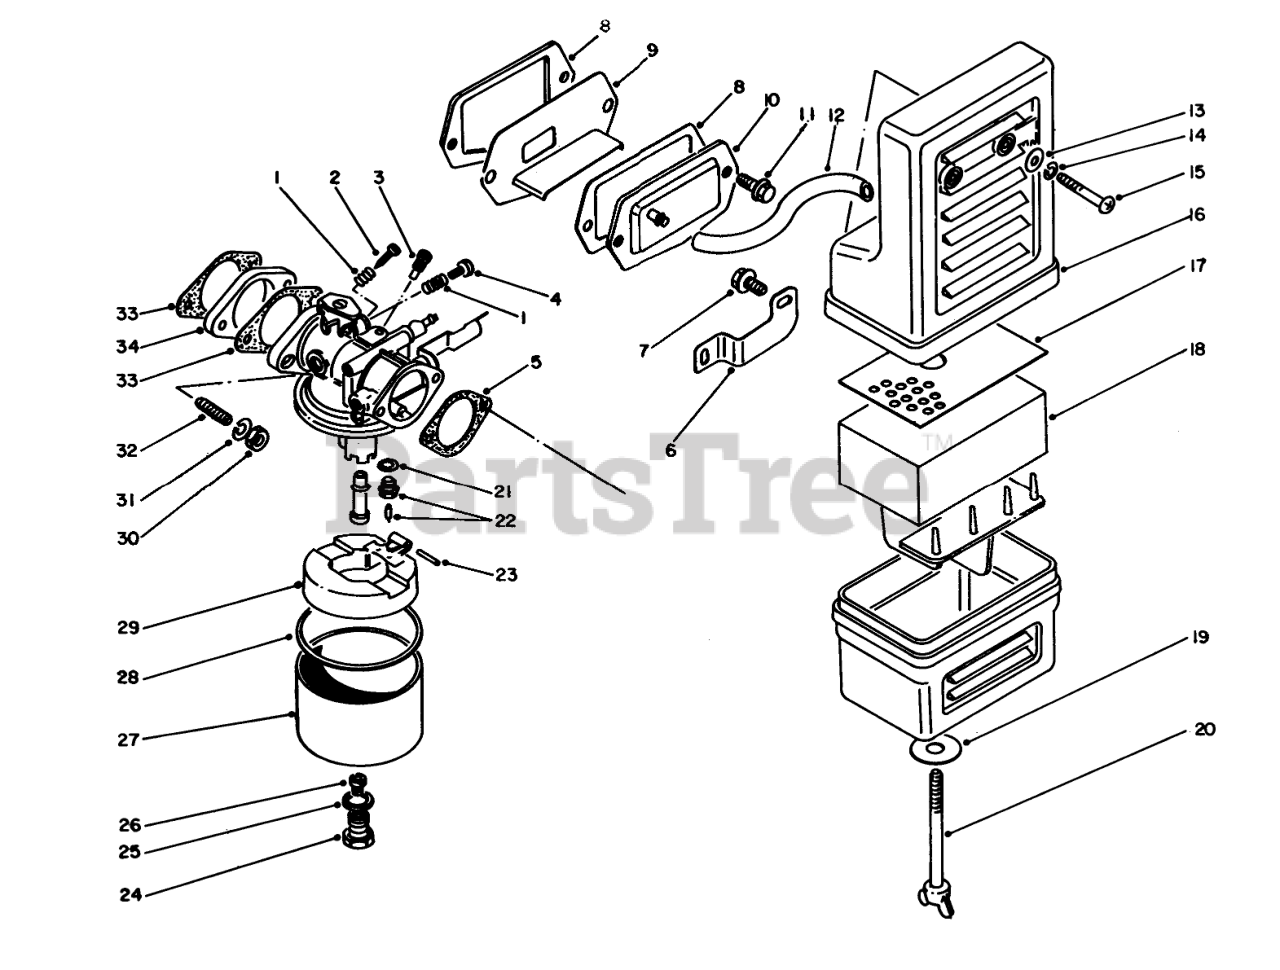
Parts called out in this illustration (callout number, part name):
1	Spring
2	Jet
3	ADJUSTER
4	Screw
5	AIR CLEANER GASKET
6	Bracket
8	GASKET
9	Reed Valve Assembly
13	WASHER
14	Washer
15	SCREW
16	Air Cleaner Assembly (Incl. Ref. #17-20)
17	Holder
18	FILTER
19	WASHER
20	Bolt-Wing
21	GASKET
22	NEEDLE VALVE
25	Gasket
26	MAIN JET
27	Carburetor Assembly (Incl. Ref. #21-26, 28, 8 29)
28	GASKET
29	Float
31	Lockwasher
32	Bolt-Stud
33	Gasket
34	INSULATOR
